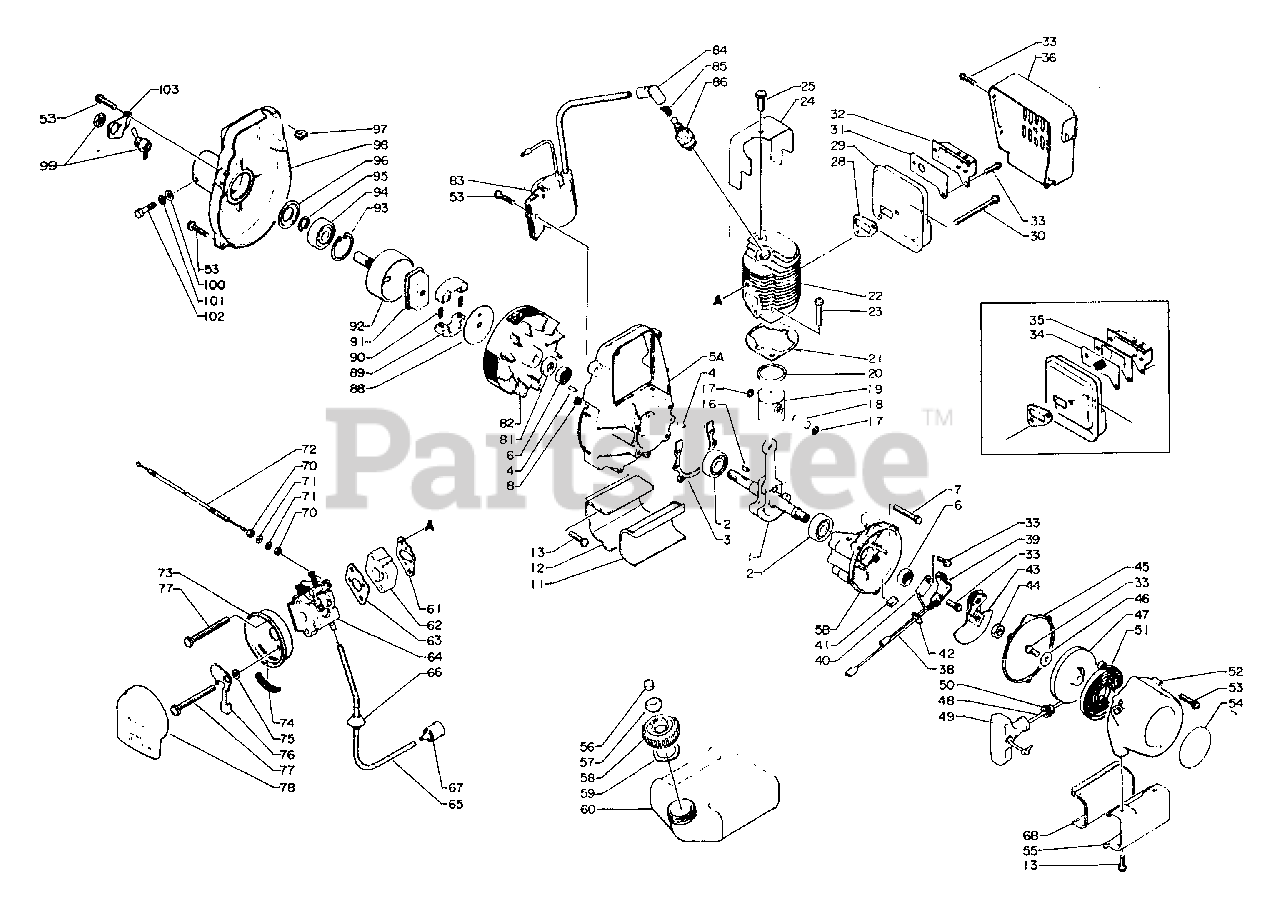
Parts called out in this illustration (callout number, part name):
1	CRANKSHAFT ASSY
2	BEARING, BALL - 6200
3	GASKET, CRANKCASE
4	PIN - LOCATING
5	CRANKCASE KIT
5A	CRANKCASE KIT
5B	CRANKCASE KIT
6	SEAL, OIL
7	SCREW - 5X30
12	BRACKET, FUEL TANK
13	SCREW - 4X14
17	RING, RETAINING
18	PIN, PISTON
19	PISTON
20	RING, PISTON
21	GASKET, CYLINDER
22	CYLINDER
23	SCREW - 6X22
24	SHIELD, CYLINDER
25	SCREW - 5X10
28	GASKET, EXHAUST
29	CASE, MUFFLER
30	SCREW - 5X40
31	GUIDE, EXHAUST - INNER
32	GUIDE, EXHAUST
33	SCREW - 4X10
34	SCREEN, SPARK ARRESTOR
35	RETAINER, SCREEN
36	COVER, MUFFLER
38	LEAD - GROUND
39	CONTACT POINT SET
40	CONDENSER
41	PAD, OIL
43	STARTER PAWL ASSY
45	GASKET, STARTER
45	STARTER ASSY
47	REEL, ROPE
48	ROPE, STARTER - 3X850
49	GRIP, STARTER
50	GUIDE, ROPE
51	SPRING, REWIND
52	CASE, STARTER
53	SCREW - 4X20
54	LABEL - ECHO
55	BRACKET, FUEL TANK
58	CAP
59	GASKET, CAP
60	TANK, FUEL
61	GASKET, INTAKE
62	INSULATOR, INTAKE
63	GASKET, INTAKE
64	CARBURETOR WA-80
65	PIPE - 3X5X195 -- BLACK
67	FILTER, FUEL
71	WASHER - 6
72	CABLE, THROTTLE
73	CASE, AIR FILTER
75	WASHER - 5
76	SHUTTER, CHOKE
77	SCREW - 5X57
78	FILTER, AIR
82	FLYWHEEL
83	COIL, IGNITION
84	CAP, SPARK PLUG
85	TERMINAL, SPARK PLUG CAP
86	SPARK PLUG -- BM-6A
88	PLATE, CLUTCH
89	SHOE, CLUTCH
90	SPRING, CLUTCH
91	HUB, CLUTCH
92	DRUM, CLUTCH
93	RING, RETAINING - 32
94	BEARING, BALL - 6201
95	RING, RETAINING - 12
96	RETAINER, PIPE
98	CASE, FAN
99	IGNITION SWITCH ASSY
100	WASHER - 5
101	LOCKWASHER - 5
102	SCREW - 5X20
103	BRACKET, SWITCH
